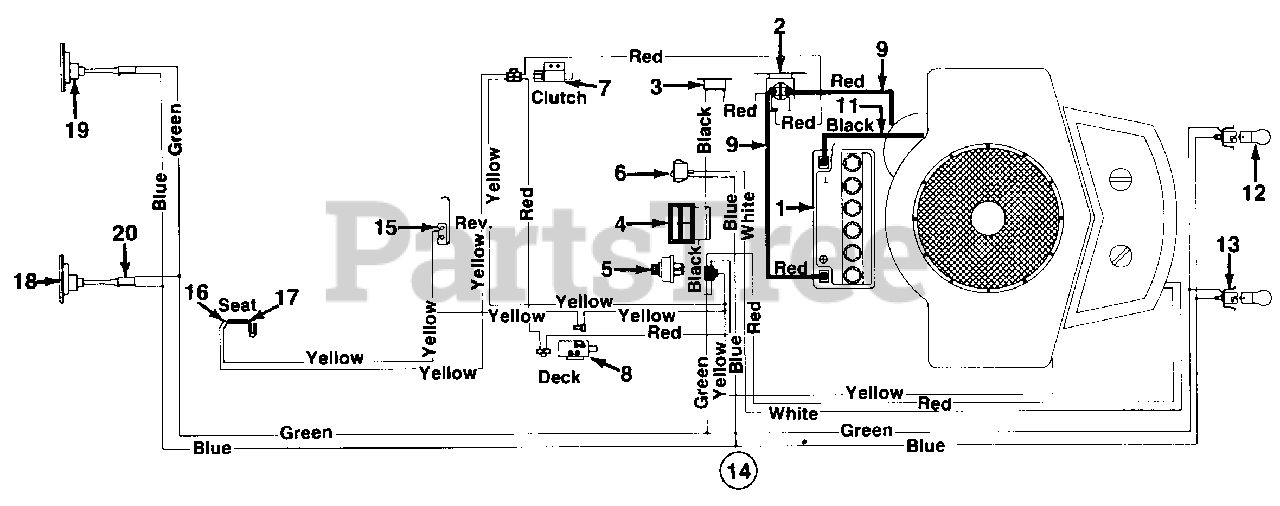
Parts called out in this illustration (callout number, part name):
1	N Battery
2	N Solenoid
3	Circuit Breaker
4	Ammeter
5	Ignition Switch
6	Light Switch
7	N Safety Switch
8	N Safety Switch
9	Electric Wire 14" Lg.
11	Ground Wire 7.5" Lg.
12	Lamp
13	Socket
14	N Wire Harness
15	Spring Switch
16	Spring Switch
17	N Spring Switch
18	Taillight Bulb
19	Taillight
20	Taillight Harness
